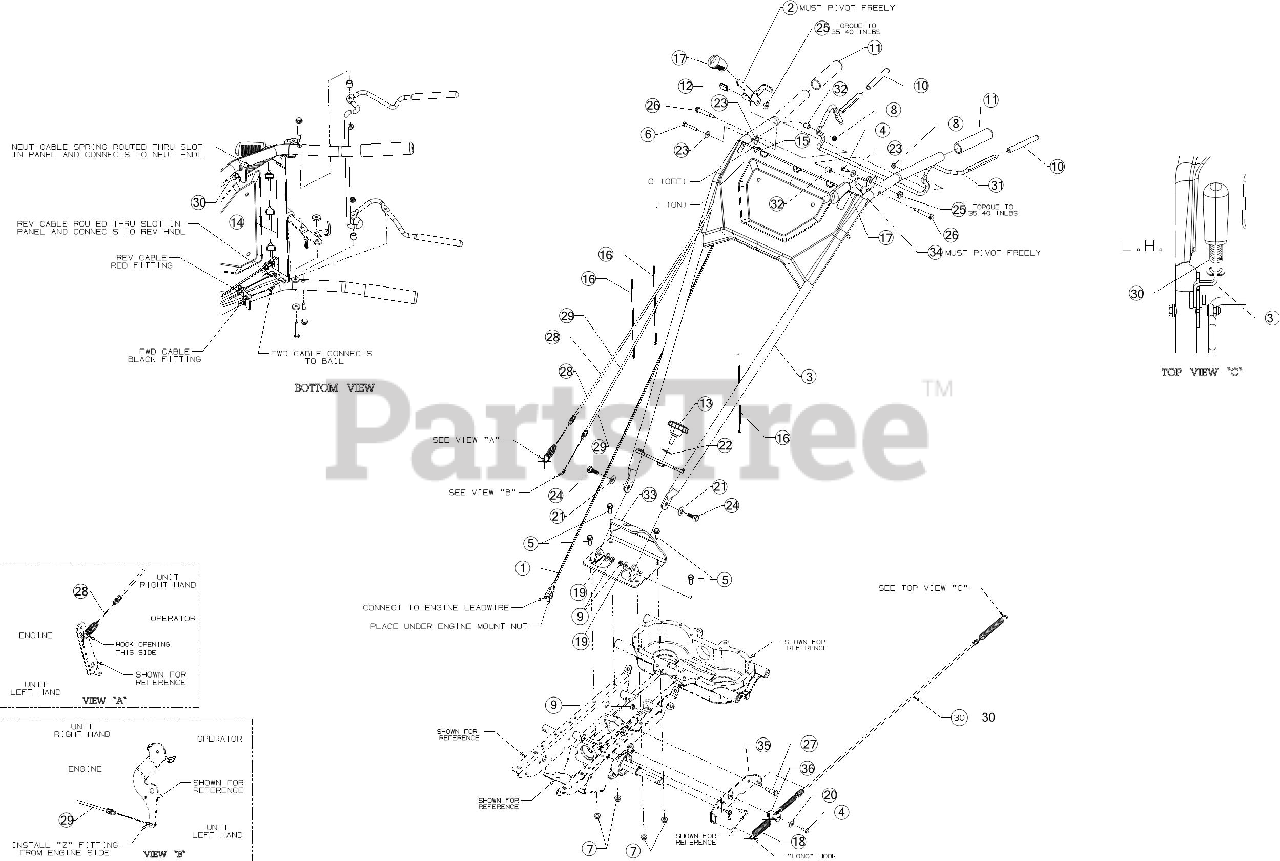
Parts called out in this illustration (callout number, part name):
1	HARNESS ADAPTER ASSEMBLY
2	REVERSE HANDLE ASSEMBLY
3	HANDLE ASSEMBLY
4	SCREW 1/4-20 x .62 SPEC GR5
5	SCREW 5/16-18 x .875 GR5
6	BOLT 1/4-20X1.62 GR5
7	FLANGE LOCK NUT 5/16-18
8	FLANGE LOCK NUT
9	HEX NUT
10	CLUTCH GRIP
13	STAR KNOB 3/8-16
14	TAPE FOAM 1.25 x 13.53 x .10
15	ROCKER SWITCH
17	BRAKE HANDLE GRIP
18	EXTENSION SPRING
19	FLAT WASHER
20	SPRING WASHER BELL
21	BELL WASHER
22	BELL WASHER
23	FLAT WASHER
24	SHOULDER SCREW .437
25	SHOULDER SPACER
26	SHOULDER SCREW .375 x 1.62 x 1/4-20
27	SHOULDER SCREW
28	FORWARD CABLE
29	REVERSE CABLE
30	NEUTRAL CABLE
33	HANDLE MOUNT PLATE
34	NEUTRAL HANDLE
35	NEUTRAL CABLE BRACKET
36	PIVOT LEVER
